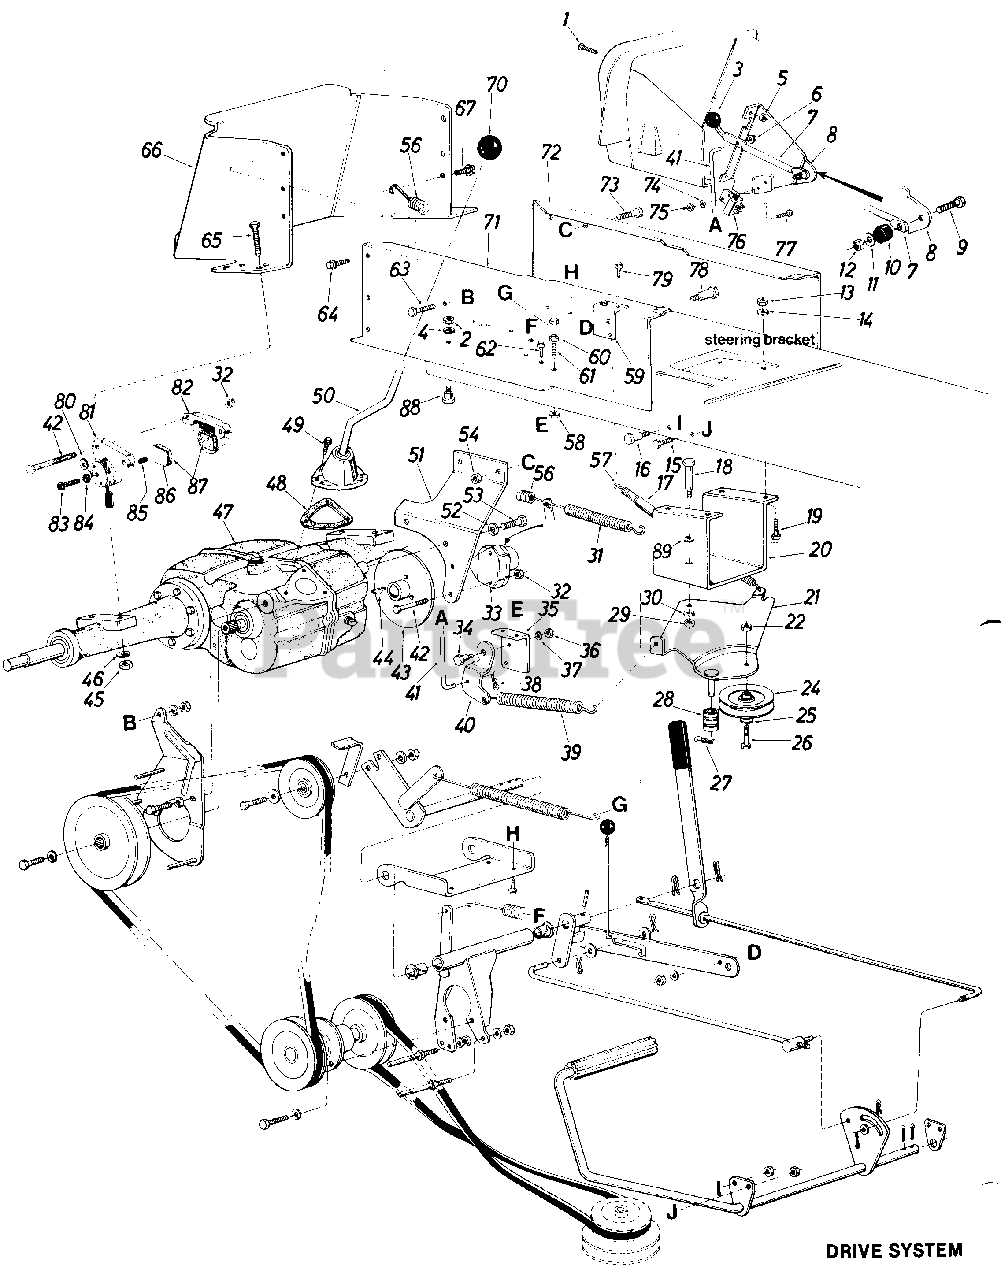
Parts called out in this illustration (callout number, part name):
1	Truss Mach. Scr. 1/4-20 x .50" Lg.
2	Hex Nut 1/4-20 Thd.*
3	Knob-Blade Clutch
4	L-Wash. 1/4 I.D.*
5	Hex Sems Nut 1/4-20 Thd.*
6	Push Cap 1/4" Rod
7	Blade Clutch Lever
8	Deck Clutch Control Brkt.
9	Hex Scr. 1/4-20 x 1.25" Lg.*
10	Rubber Wash. .330 I.D. x .87
11	Fl-Wash. 1/4" I.D. x .75" O.D. x .057
12	Hex Cent. L-Nut 1/4-20 Thd.
13	Hex Nut 5/16-18 Thd.
14	L-Wash. 5/16" Scr.
15	Hex Scr. 3/8-16 x .62" Lg.
16	Shld. Scr. 1/2" Dia. x .335 Lg. 3/8-16
17	Convoluted Conduit .50 I.D. x4" Lg.
18	Shld. Scr. 7/16 Dia. x .16" 5/16-18
19	Hex Scr. 5/16-18 x 1.00" Lg.
20	Idler Mtg. Brkt.-Deck
21	Idler Brkt. Ass'y.
22	Hex L-Nut 3/8-16 Thd.
24	4"-"V" Idler Pulley
25	Fl-Wash. 3/8" I.D.
26	Hex Scr. 3/8-16 x 1.25" Lg.
27	Hairpin Cotter 5/16" Rod
28	Spacer
29	Hex Nut 5/16-18 Thd.
30	L-Wash. 5/16" Scr.
31	Ext. Spring-Brake Rod
32	Hex Cent. L-Nut 3/8-16 Thd.
33	Disc Brake Caliper Ass'y.
34	Shld. Scr. 7/16" Dia. x .16" Lg. 5/16-18
35	Parking Brake Cam Mtg. Brkt.
36	Hex Nut 5/16-18 Thd.
37	L-Wash. 5/16" Scr.*
38	Hairpin Cotter 5/16" Dia.
39	Ext. Spring-Deck Control
40	Deck Control Pivot Brkt.
41	Deck Control Rod
42	Hex Scr. 3/8-16 x 2.50" Lg.
43	Hub & Disc Ass'y.
44	Hi-Pro Key 3/16 x 3/4" Lg.
45	Hex Nut 3/8-16 Thd. *
46	L-Wash. 3/8" Scr.*
47	Transaxle
51	Transaxle Support
52	L-Wash. 3/8" Scr.
53	Hex Scr. 3/8-16 x .75" Lg.
54	Hex L-Nut 3/8-16 Thd.
56	Ext. Spring-Brake Return
57	Ext. Spring-Deck Idler Return
58	Hex L-Nut 5/16-18 Thd.
59	Parking Brake Cam Mtg. Brkt.
60	Hex Nut 5/16-18 Thd.*
61	Hex Scr. 5/16-18 x 1.50" Lg.
62	Hex Thd. Rolling Scr. 1/4-20 x.50" Lg.
63	Hex Scr. 3/8-16 x .75" Lg.
64	Hex AB-Tap Scr. 5/16 x .75" Lg.
65	Hex Scr. 3/8-16 x 1.50" Lg.
66	Hitch Plate
67	Hex Thd. Rolling Scr. 5/16-24 x .75" Lg.
70	Knob-Transaxle
71	Side Panel Upper Frame-R.H.
72	Side Panel Upper Frame-L.H.
73	Hex Scr. 3/8-16 x .75" Lg.
74	Ext. L-Wash. #10 Scr.
75	Hex Nut #10-24 Thd.
76	Safety Switch
77	Truss Mach. Scr. #10-24 x .50" Lg.*
78	Shld. Scr. 7/16" Dia. x .16" Lg. 5/16-18
79	Hex Thd. Rolling Scr. 1/4-20 x.50" Lg.
81	11ousing with Lever & Pin
83	Pin, Adjuster
84	Nut
85	Pin, Actuator
86	Backing Plate
87	Lining
88	Shld. Bolt .375" Dia. x .180" Lg. 1/4-20 Thd.
89	Wave Washer
